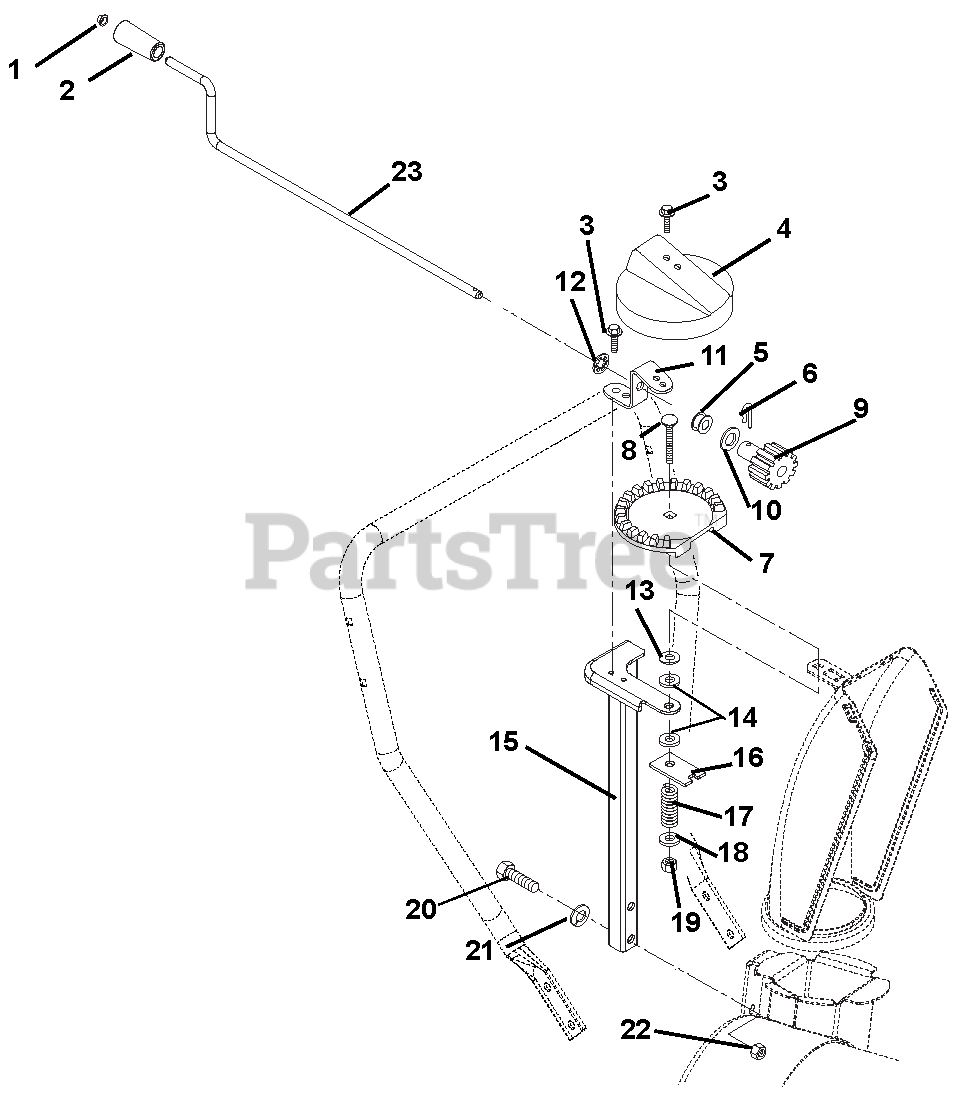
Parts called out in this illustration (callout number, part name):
1	CAP, 3/8 ROD YWZC
2	KNOB, CHUTE CRANK
3	SCR-TAP .25-20X.50 HWH TR YWZ
4	GEAR COVER
5	BUSHING, POLYLINER-.63 SNAPIN
6	PIN, SPRING CLIP
7	CHUTE GEAR
8	@BLT-RDHDSQNK .38-16X2.50 G5YZ
9	PINION GEAR W/BRACKET
10	WSHR-THRST .625 X 1.0 X .03
11	BRACKET, PINION GEAR
12	PUSHNUT .625
13	WSHR-FL-STL .380X1.50X.062 YWZ
14	FRICTION WASHER
15	CHUTE PEDESTAL, TALL COMPACT
16	PLATE, FRICTION
17	SG-COMP .187X.56X1.62
18	@WSHR-FL-STL.406X.812X.065 YWZ
19	@NUT-LK-CTR .38-16 YWZC
20	@BLT-HEX .38-16X1.75 GR5 YWZC
21	@WSHR-LK .38X.094 REG YWZC
22	@NUT-LK-TOP-FLG .38-16 YWZC
23	CHUTE CRANK,COMPACT 920,XXX HI
